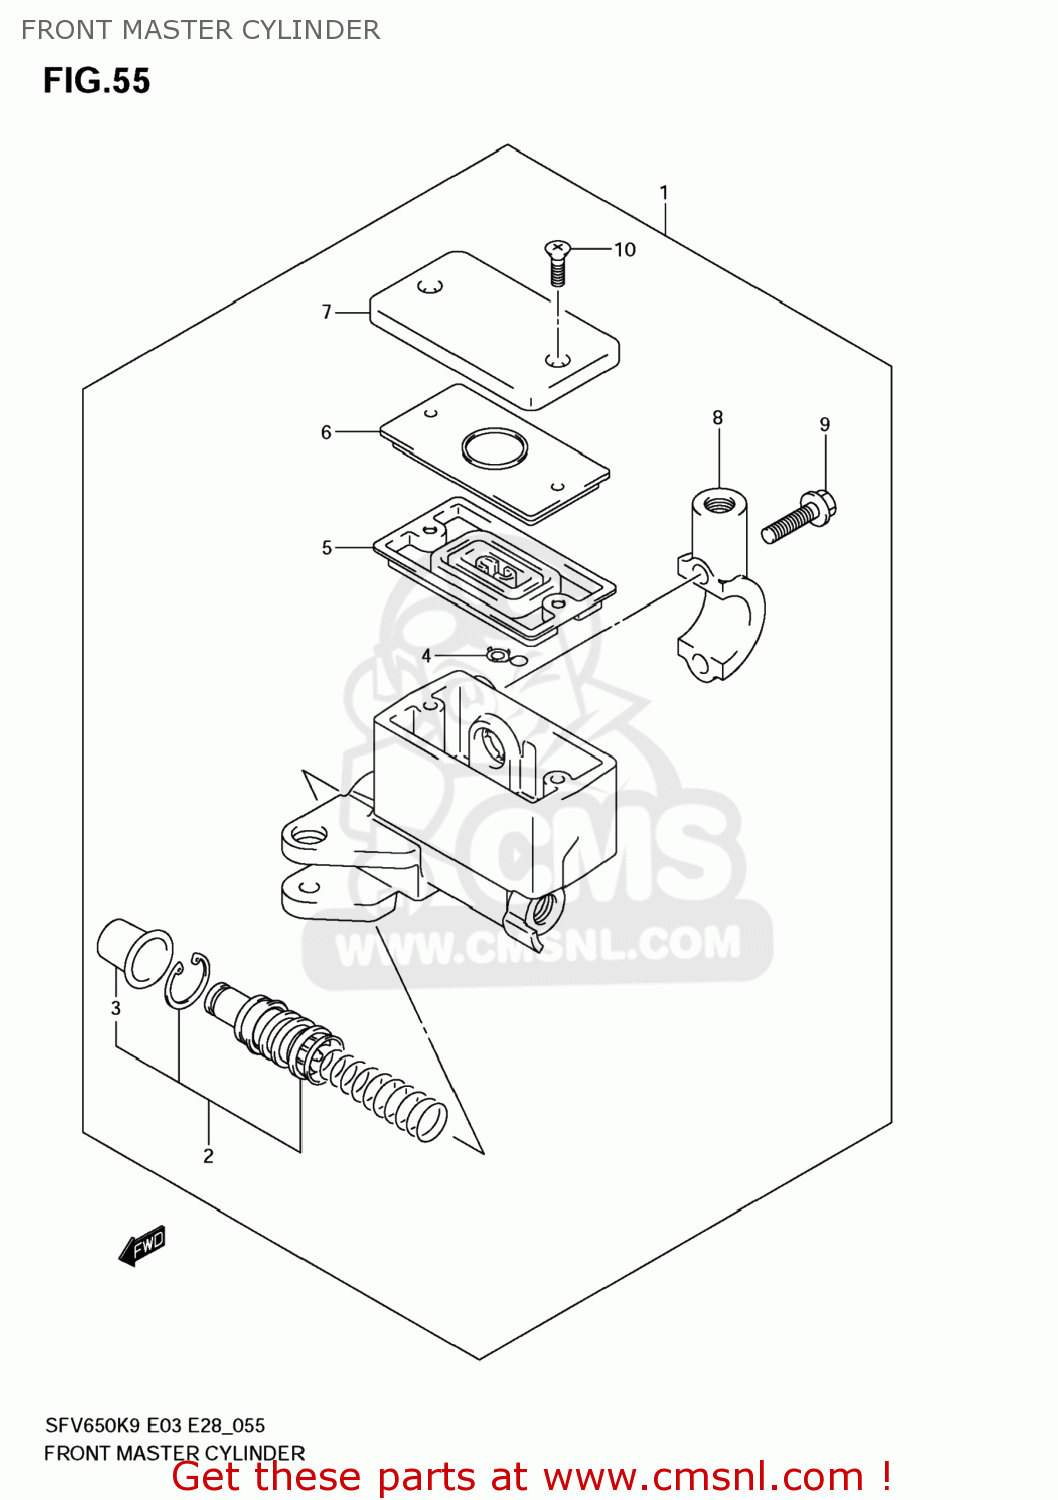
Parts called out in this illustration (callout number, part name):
1	CYLINDER ASSY,FR MASTER
2	PISTON & CUP SET
3	BOOT
4	PROTECTOR
5	6
6	PLATE,DIAPHRAGM
7	CAP
8	HOLDER
9	BOLT(6X22)
10	SCREW
